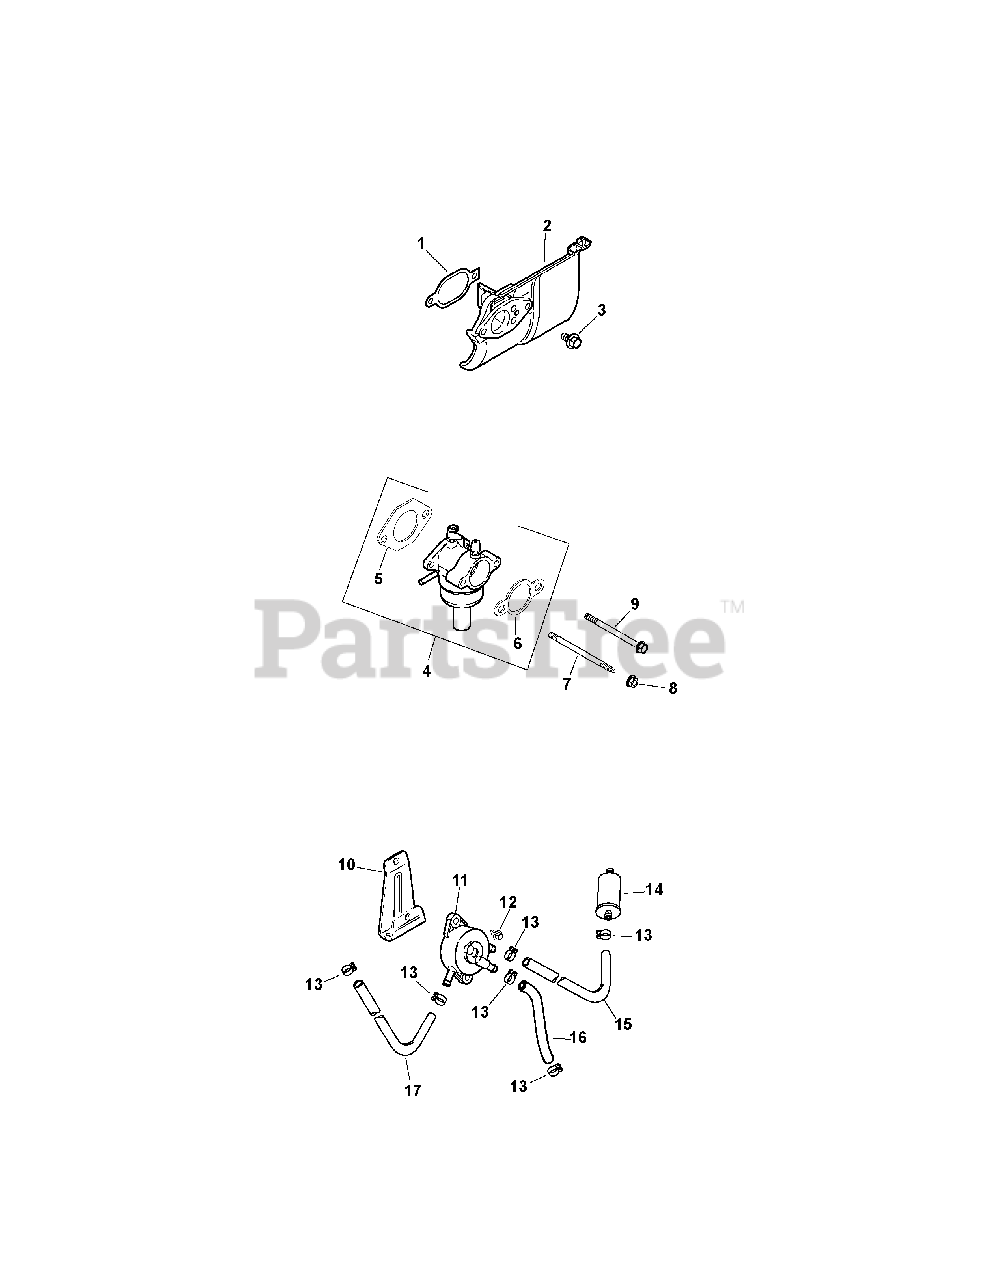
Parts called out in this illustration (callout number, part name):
1	Heat Deflector Gasket
2	Heat Deflector
3	Hex Flange Screw (M6 x 1.0 x 20)
4	Carburetor w/Gaskets
5	Carburetor Gasket
6	Air Cleaner Gasket
7	Carb Mounting Stud
8	Hex Flange Nut (M6 x 1.0)
9	Carb Screw (S60 x 1.42 x 85)
10	Fuel Pump Mounting Bracket
11	Fuel Pump Assembly
12	Hex Flange Screw (M5 x .8 x 10)
13	Hose Clamp
14	Fuel Filter
15	Fuel Line 4"
16	Fuel Line 10"
17	Fuel Line 15-3/4"
